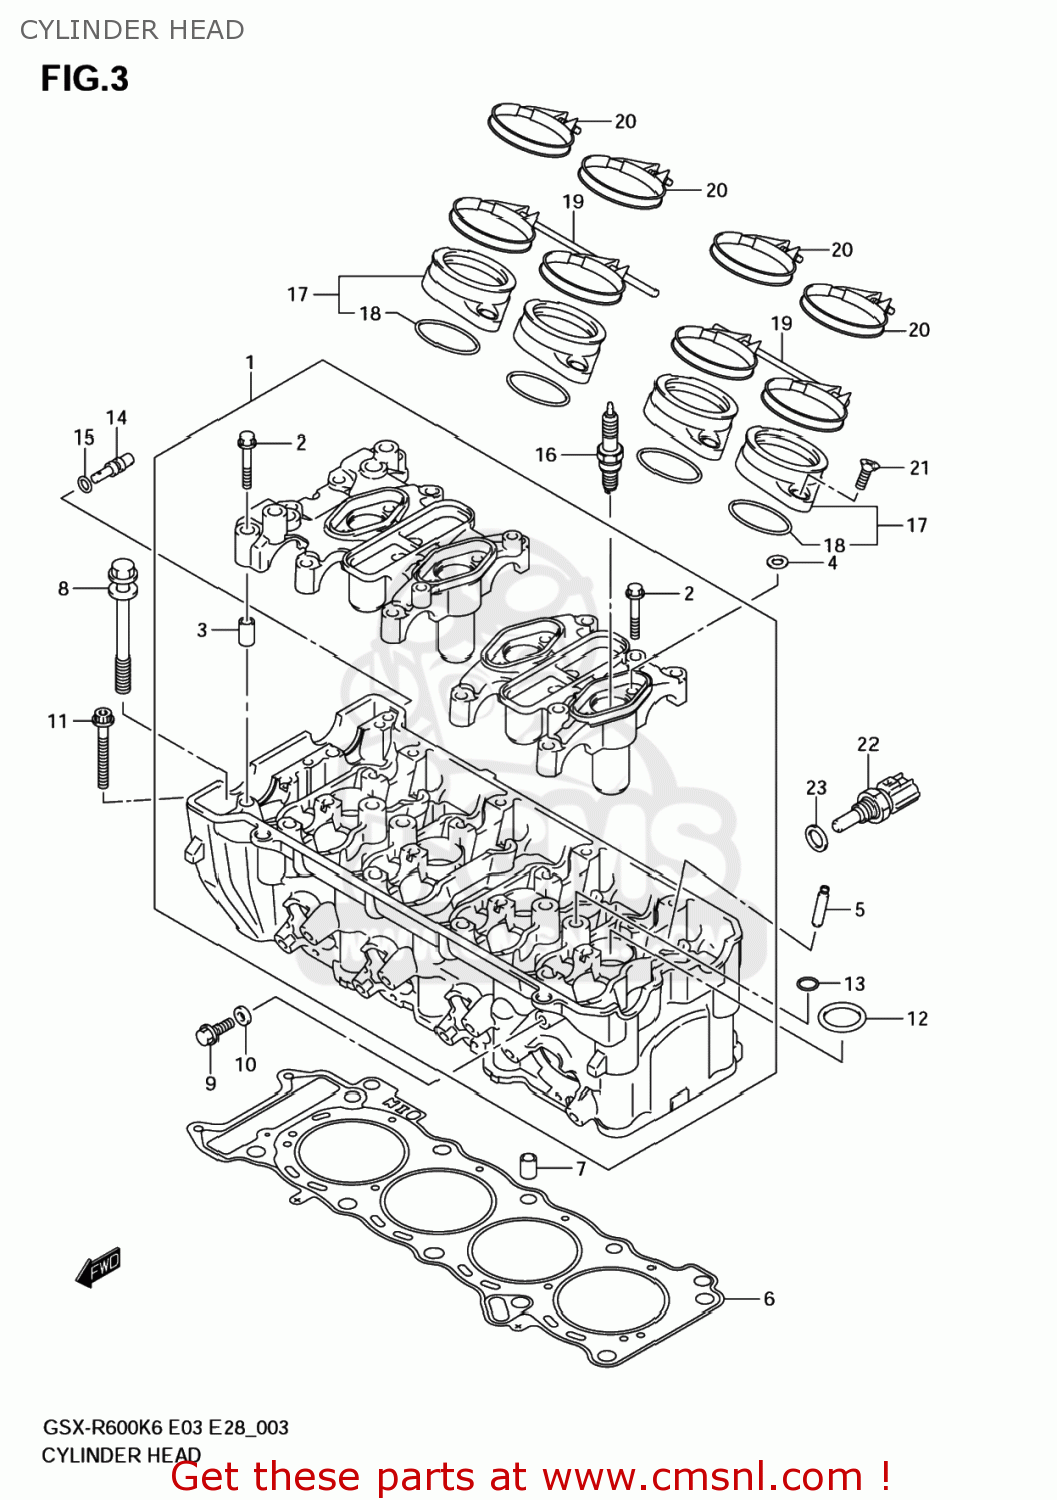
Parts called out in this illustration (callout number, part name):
1	HEAD ASSY,CYLINDER
2	BOLT(6X40)
3	PIN(6.2X8X16)
4	GASKET(6.2X13X1.2) (NAS)
5	GUIDE,VALVE(OS:0.3)
6	GASKET,CYLINDER HEAD (NAS)
7	PIN
8	BOLT,CYLINDER HEAD
9	BOLT(6X12)
10	GASKET(5.8X13X1.2) (NAS)
11	BOLT
12	O-RING
13	O RING(D:2.4,ID:10.8)
14	JET(8)
15	O RING(D:1.2,ID:4)
16	PLUG,SPARK(CR8E)
17	PIPE ASSY,INTAKE
18	O RING(D:2.4,ID:41.7)
19	CLAMP COMP,INT
20	CLAMP
21	SCREW (86X15.4
22	SENSOR,WATER TEMP
23	GASKET(12X17X1) (NAS)
